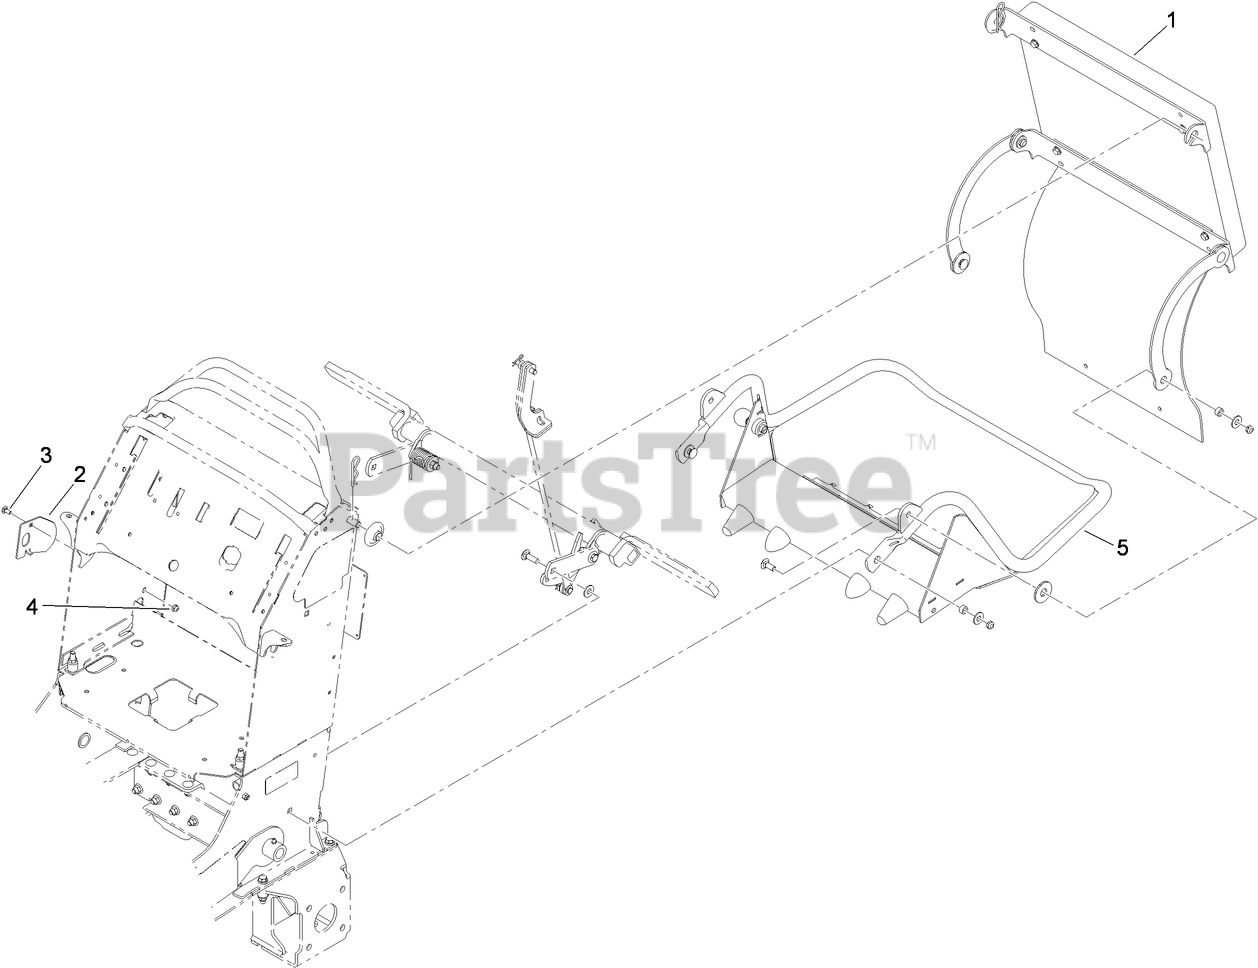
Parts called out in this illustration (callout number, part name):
1	CUSHION ASM
2	PLATE-STRIKER
3	SCREW-CARR
4	NUT-HF
5	PLATFORM ASM
